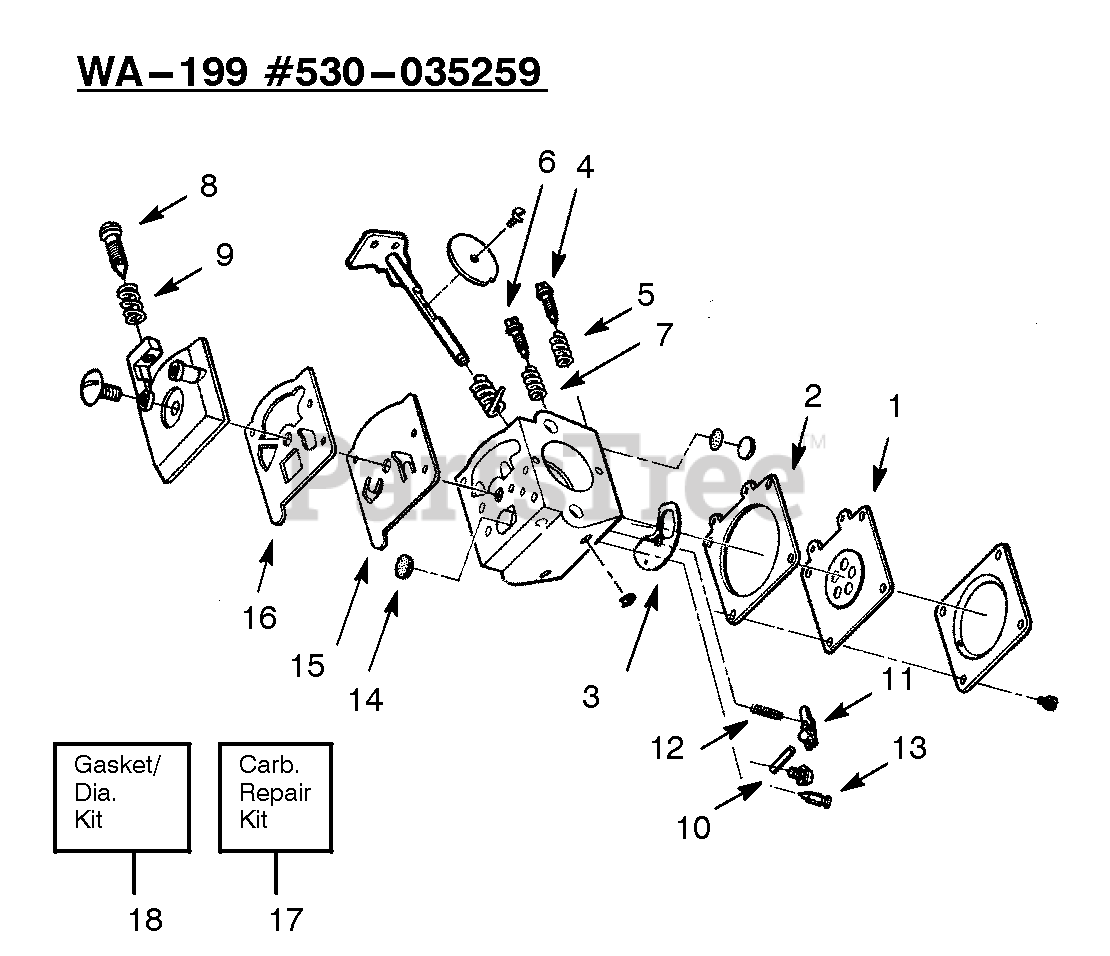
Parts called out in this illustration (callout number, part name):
1	Metering Diaphragm
2	Metering Diaphragm Gasket
3	Circuit Plate Gasket
4	Hi Speed Needle
5	Hi Speed Needle Spring
6	Idle Needle
7	Idle Needle Spring
8	Idle Speed Screw
9	Idle Speed Spring
10	Metering Lever Pin
11	Metering Lever
12	Metering Lever Spring
13	Inlet Needle Valve
14	Inlet Screen
15	Pump Diaphragm
16	Pump Gasket
17	Carb. Kwik Repair Kit
18	Carb. Gasket/DiaphragmKit
